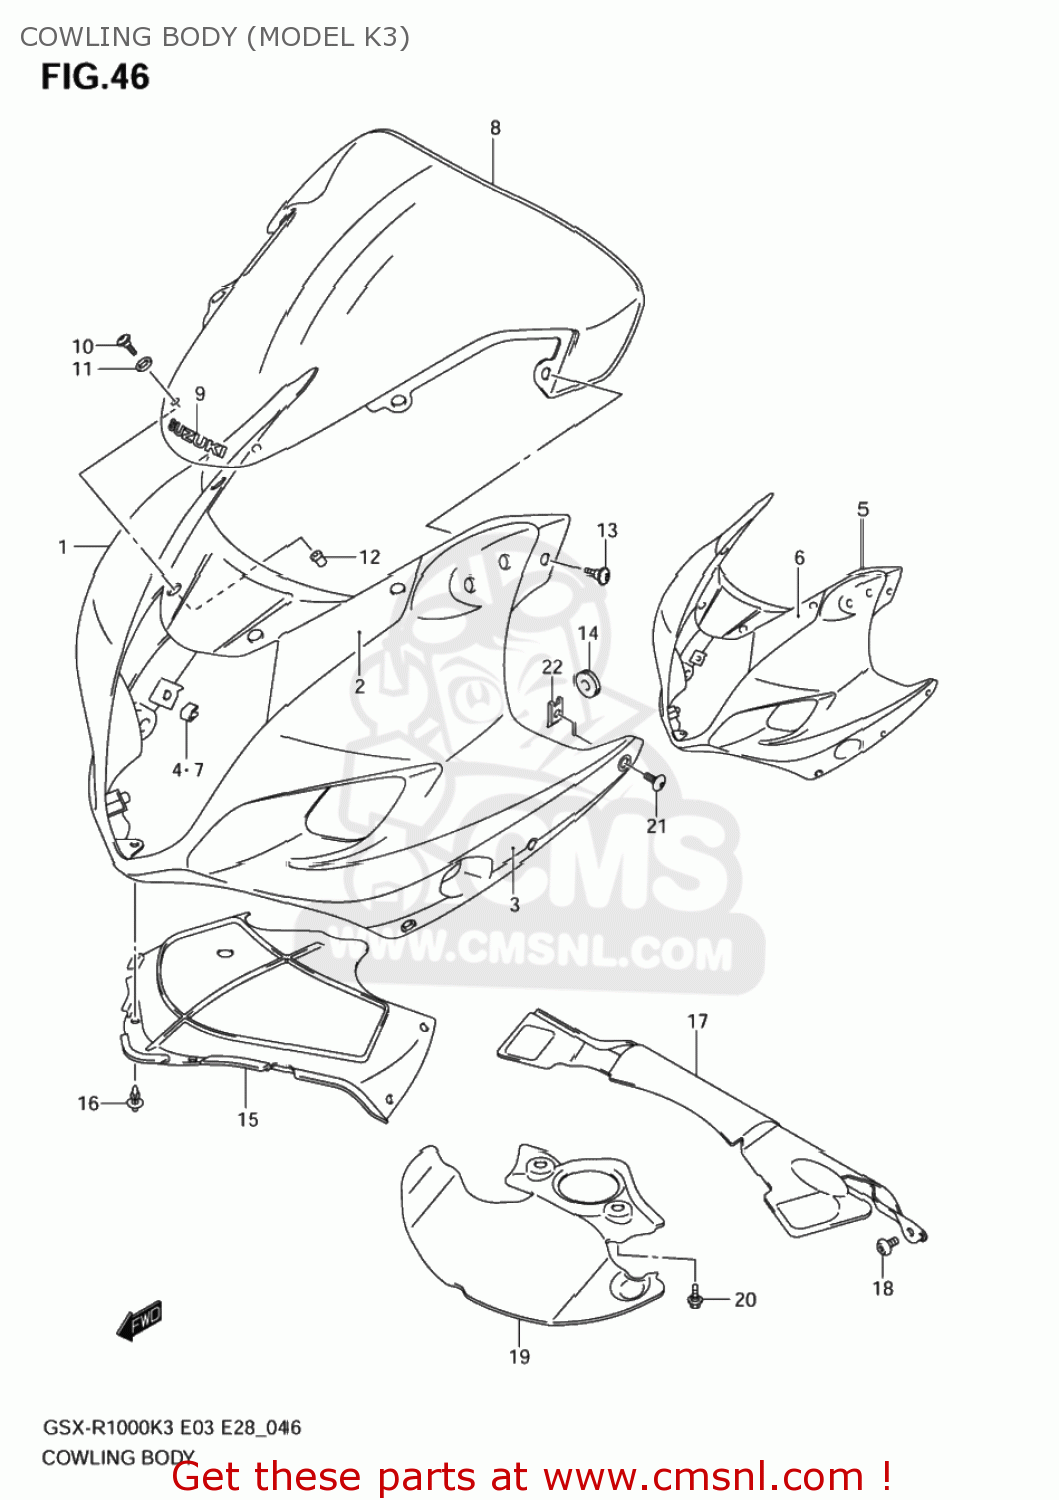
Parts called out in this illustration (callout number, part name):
1	COWLING,BODY(BLUE)
2	TAPE,COWL BODY FR
3	TAPE SET,COWL BODY SIDE
4	CUSHION,FR LEG COVER
5	COWLING,BODY(SILVER)
6	TAPE,COWL BODY FR
7	CUSHION,FR LEG COVER
8	WINDSCREEN
9	TAPE,WINDSCREEN
10	SCREW(5X14)
11	WASHER
12	NUT
13	SCREW(5X16)
14	CUSHION
15	COVER,BODY COWLING
16	CLIP(BLACK)
17	COVER,COWLING FR LWR
18	BOLT(5X13)
19	COVER,LWR BRACKET
20	BOLT
21	SCREW(5X13)
22	NUT,COWL
